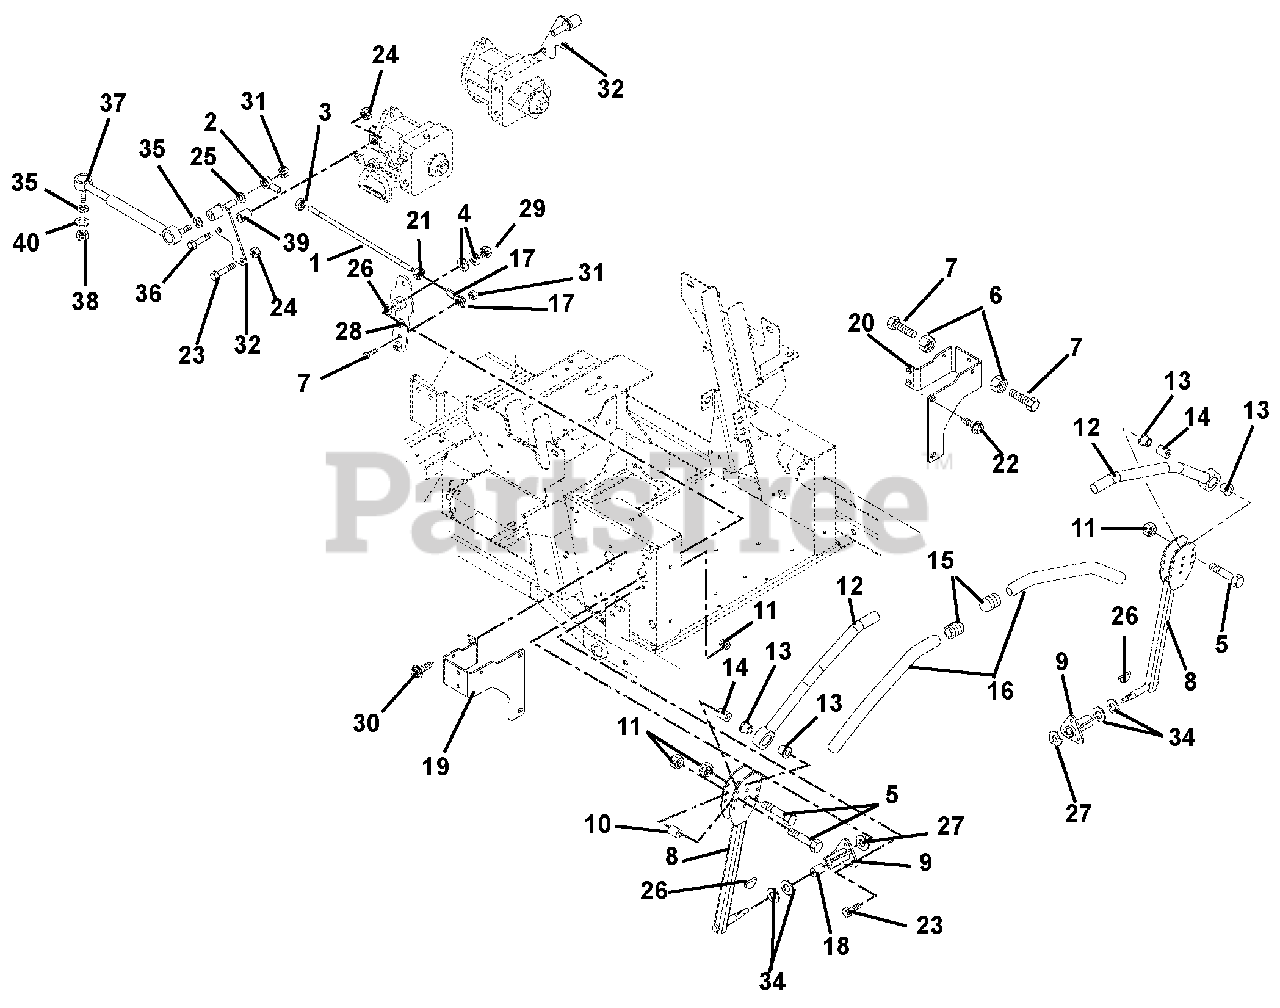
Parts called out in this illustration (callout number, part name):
1	Tie Rod Assembly
2	Rod End, .38 Right Hand
3	Nut, Jam .375-24
4	Washer, Flat Steel .408 x .812 x .065
5	Bolt, Hex .31-18 x 1.75 Grade 5
6	Nut, Hex Jam .375-16
7	Bolt, Hex .375-16 x 1.75
8	Weldment, Control Arm
9	Bushing, Flange
10	Eccentric
11	Nut, Locking Top Flange .31-18
12	Handle Weldment-Left Hand
13	Bushing, Flange Nylon .762 x 1.48 x .44
15	Caplug, Handlebar
16	Grip, Handlebar
17	Rod End, .38 Left Hand
18	Bushing .625 x .75 x .50
19	Bracket, Stop Right Hand
20	Bracket, Stop Left Hand
21	Nut, Jam .375-24 Left Hand
22	Screw, Tapping .38-16 x .75 Hex Washer Head
23	Bolt, Hex .31-18 x .75 Grade 5
24	Nut, Locking Top Flange .31-18
25	Washer, Locking .38 x .094 Regular
26	Key, Woodruff .13 x .63
27	Washer, Wave
28	Weldment, Pivot Arm
29	Nut, Locking Top Flange .38-16
30	Screw, Tapping .38-16 x .50 Hex Washer Head
31	Nut, Locking Jam Center .375-16
32	Weldment, Return to Neutral/Damper/Rod End
33	Bolt, Hex .38-16 x 1.25 Grade 5
34	Washer, Flat Steel .63 x 1.005 x .062
35	Washer, Locking .31 x .078
36	Bolt-Hex .31-18 x 1.25 Grade 5
37	Damper, Control
38	Nut-Locking-Nylon M8-1.25
39	Spacer .318 x .43 x .375
40	Washer, Flat Steel .38 x .875 x .083
